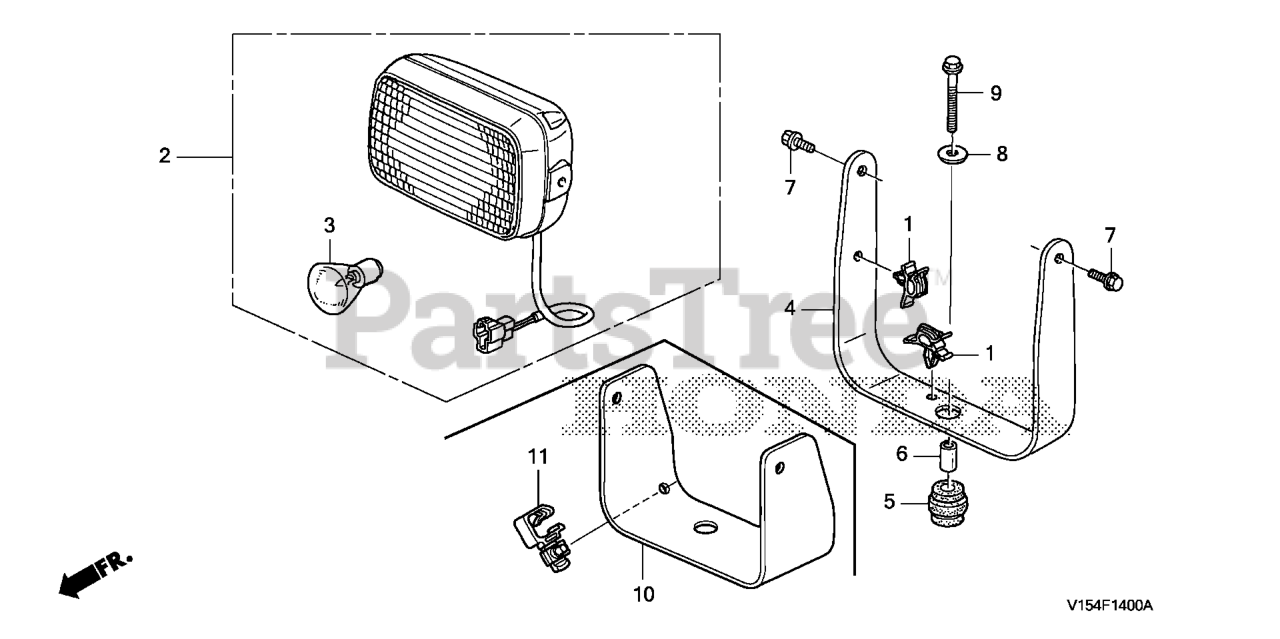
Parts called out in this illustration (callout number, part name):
2	LIGHT ASSY., WORKING
3	BULB, WORKING LIGHT
5	RUBBER, HEADLIGHT MOUNTING
6	COLLAR, CUSHION RUBBER BUSH (SHOWA)
7	BOLT-WASHER (6X14)
8	WASHER, PLAIN (8MM)
9	BOLT, FLANGE (8X35)
10	BRACKET, HEADLIGHT
11	CLIP, HARNESS (5MM-15MM) (BLACK)
